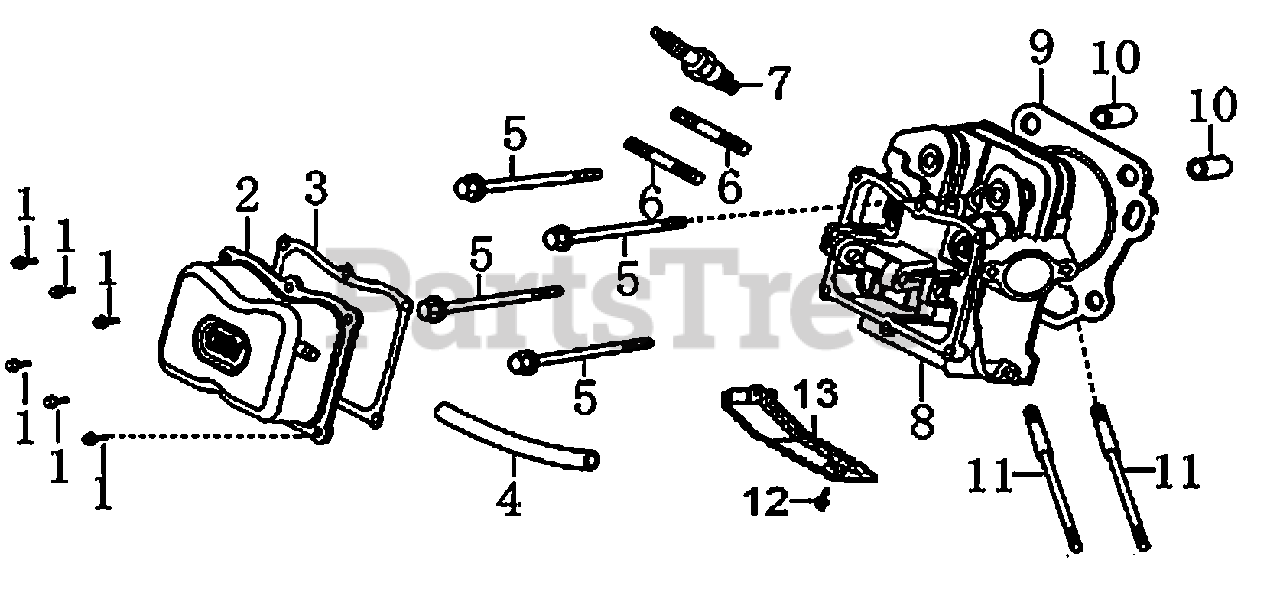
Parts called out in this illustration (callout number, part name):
1	BOLT, FLANGE
2	COVER COMP. HEAD
3	GASKET, HEAD COVER
4	TUBE, BREATHER
5	BOLT, FLANGE, 10×80
6	BOLT, STUD, EXHAUST
7	SPARK PLUG
8	CYLINDER HEAD COMP
9	GASKET, CYLINDER HEAD
10	PIN, DOWEL
11	BOLT, STUD, INTAKE
12	BOLT, FLANGE M6×12
